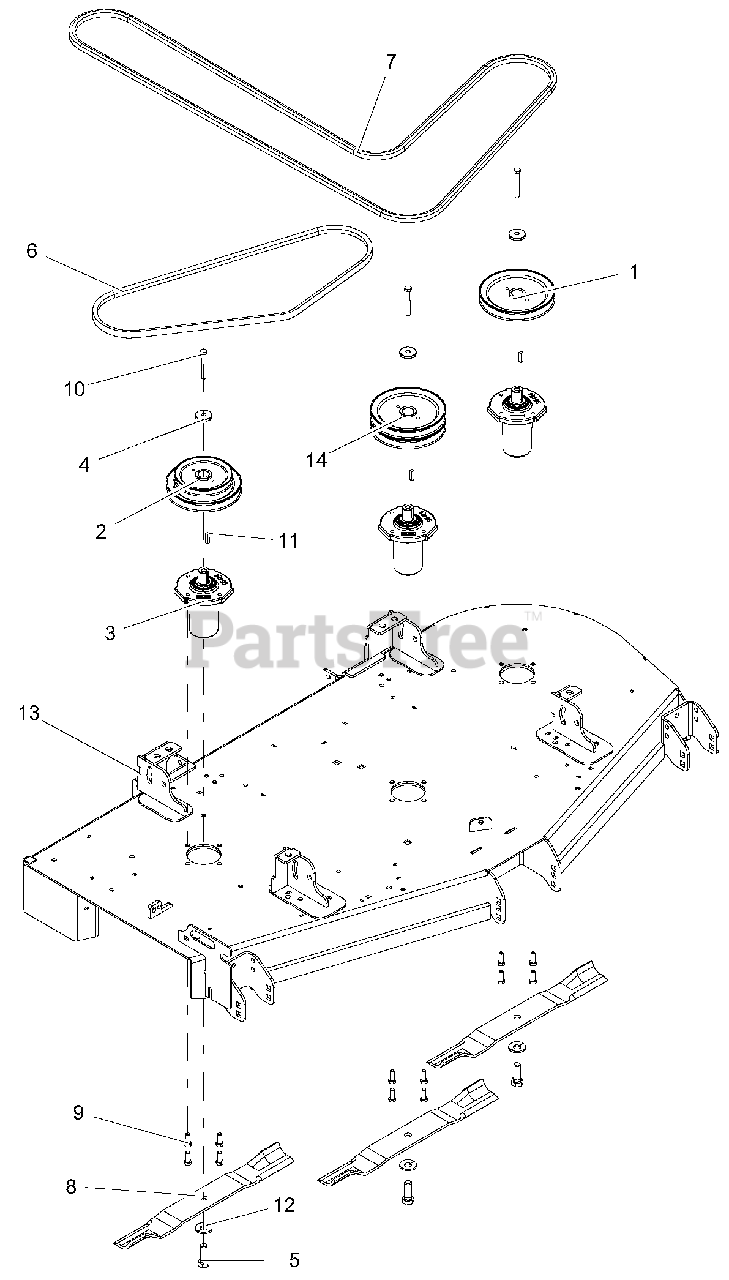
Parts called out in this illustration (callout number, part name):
1	PULLEY, V-1" ID X 6.75" OD-BLACK
2	PULLEY, DOUBLE -1" ID X 6.75" & 5.25" OD
3	SERVICE, ASM SPINDLE- DUCTILE
4	RETAINER, SHEAVE SPEINDL
5	BLT, HEX .62-18X1.75 GR8 YWZC
6	BELT, B 63.00 RAW COGGED
7	BELT, BB 118.00 WRAPPED HEX
8	BLADE, MOWER 60"
9	BLT-HEX .38-16X1.00 GR5 YWZC EP30
10	BLT-HEX .38-16X2.75 GR8 YWZC
11	KEY-SQ .250X.250X1.00 RC 40-50
12	WSHR, BLVL .63X1.625X.14
13	KIT-60 MOWER DCK W/ SAFE DECAL
14	PULLEY, DOUBLE 1"ID X 6.75"OD-BLACK
